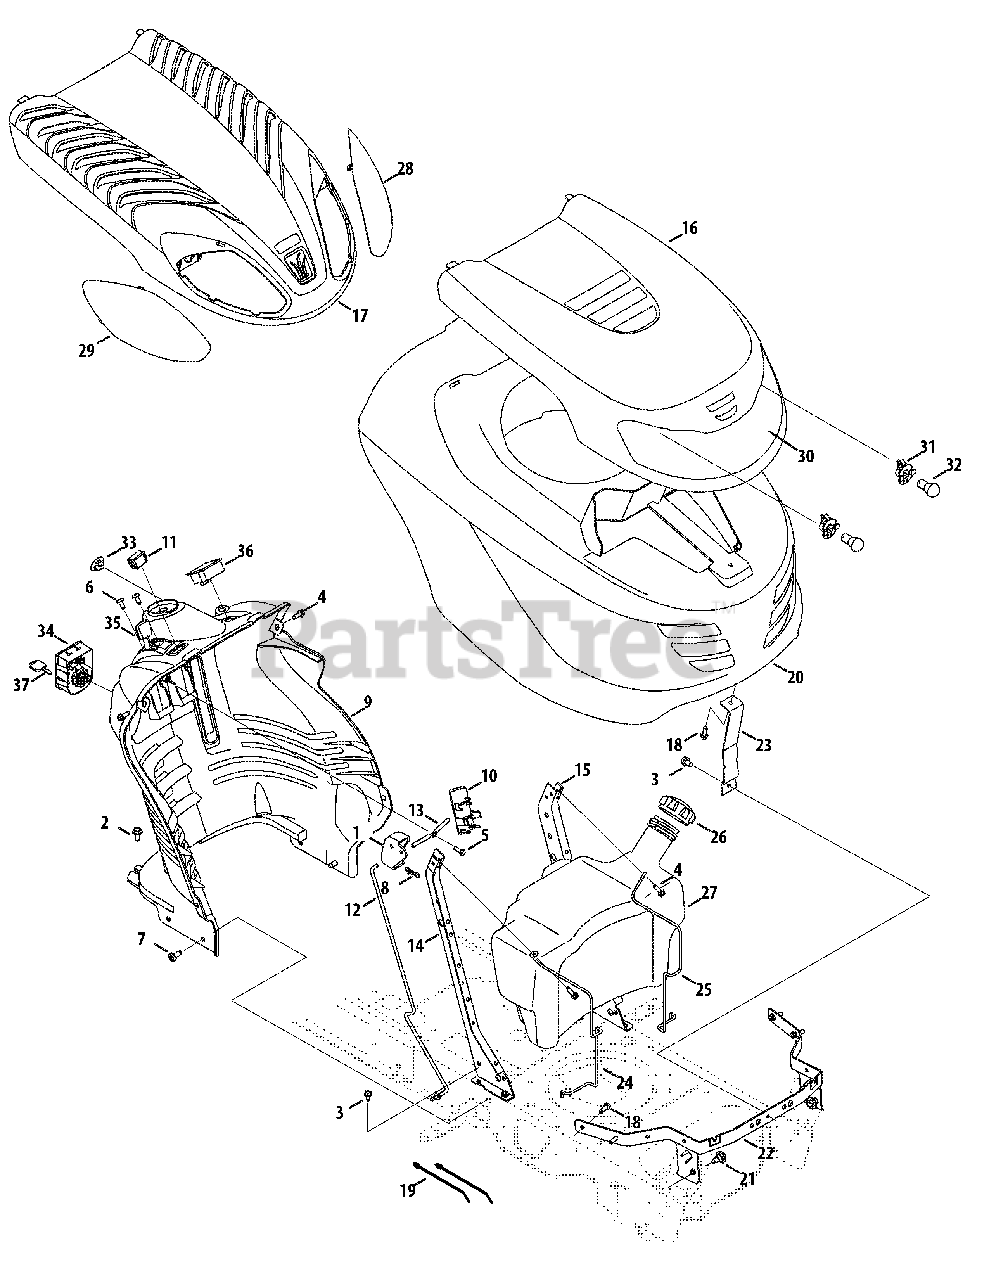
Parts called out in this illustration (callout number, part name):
1	Lever, Dash, Y/G Style
2	Screw, Self-tapping, 5/16-18, .750,
3	Screw, Self-tapping, 1/4-20, 0.500,
4	Screw, Self-tapping, 1/4-20, 0.750,
5	Screw, HL, 1/4-15, 0.750,
6	Screw, Ab, 1/4-14, 0.625
7	Screw, Self-tapping, 5/16-18, 0.750
8	Pin, Cotter, Bow-Tie 72
9	Panel, Dash, Man PTO
10	Cover, Cruise, Y/G Style
11	Cap, Light Switch Null
12	Rod, Control, Latch
13	Rod, Lever, Brake/Cruise Pivot
14	Support, Dash, Plate, RH
15	Support, Dash, Plate LH
16	Hood, Upper, G-Style
17	Hood, Upper, Y-Style (Yellow)
17	Hood, Upper, Y-Style (Gray)
18	Screw, Bos, 1/4 Dia, .750,
19	Tie, Cable, Push Mount 7.5
20	Hood, Side Tank, Y-Style
20	Hood, Side Tank, Y-Style (Gray)
21	Screw, Shoulder, .43x.29, 5/16-18
22	Bracket, Pivot, Hood
23	Bracket, Support, Hood
24	Rod, Support, RH Tank
25	Rod, Support, LH Tank
26	Cap, Fuel
27	Tank, Fuel, 2.75 Gal
28	Lens, Y-Style, LH
29	Lens, Y-Style, RH
30	Lens, Hood, G-Style
31	Socket, Lamp
32	Lamp, 12v
33	Plug, Choke
34	Module Switch, Ignition
35	Cable, Throttle/Choke
36	Meter, Indicator
37	Key, Ignition
